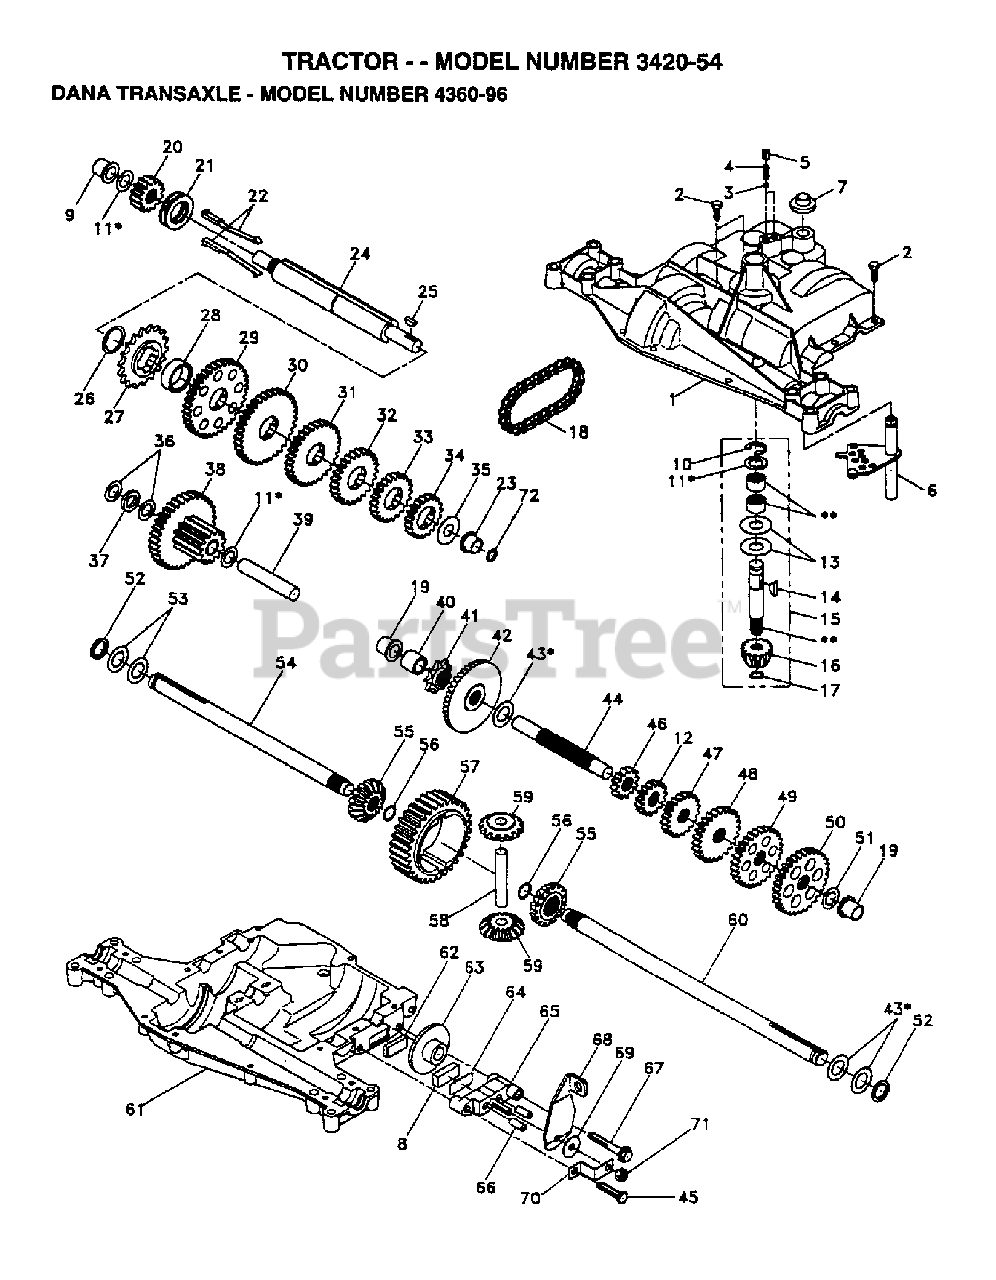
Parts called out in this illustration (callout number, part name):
1	IGNITION HARNESS
2	Poulan TBD
4	SPRING, DETENT
6	SHIFTER KIT
7	BOOT, SHIFTER
8	PUCK, FRICTION
10	Poulan TBD
11	SHIM.KIT.DANA.4689
12	PLUG PLASTIC
13	WASHER.PLAIN..632X1.38X.046
14	KEY.WOODRUFF.DANA
15	ASSY, KIT INPUT SHAFT
16	PIN, BEVEL, 14T YT
17	RING RETAINING
18	CHAIN 24 PITCH LT
19	BEARING, FLANGE LT
20	GEAR SPUR 14 TTH
23	BEARING.FLANGE (DANA 5511)
24	SHAFT INTERM DANA
26	RING, RETAINING LT
27	SPROCKET 18T
29	GEAR, SPUR 37 TEETH
30	GEAR, SPUR 35 TEETH
32	GEAR, SPUR 25 TEETH
33	GEAR, SPUR 22 TEETH
36	WASHER 025
38	ASSM GEAR COMB T NLA
39	SHAFT IDLER
41	SPROCKET 9T LT
42	GEAR, SPUR 42T YT
44	SHAFT, DRIVE
46	GEAR SPUR 12 TEETH
49	GEAR, SPUR 28 TEETH
50	GEAR, SPUR 31 TEETH
52	NEOPRENE.WASHER.DANA
53	WASHER 031
54	AXLE T, LH
55	GEAR 15T T
56	RING, RETAINING
59	GEAR 1ST T
61	LOWER HOUSING
62	PUCK, FRICTION
63	BRAKE DISC T
64	SPACER LT
65	JAW T
67	SCREW, SELF TAPPING, LARGE
69	WASHER, PLAIN .321 X 1.00X.055
70	BRACKET, ANTI ROTATION
71	LOCKNUT
73	SHELL, GREASE
